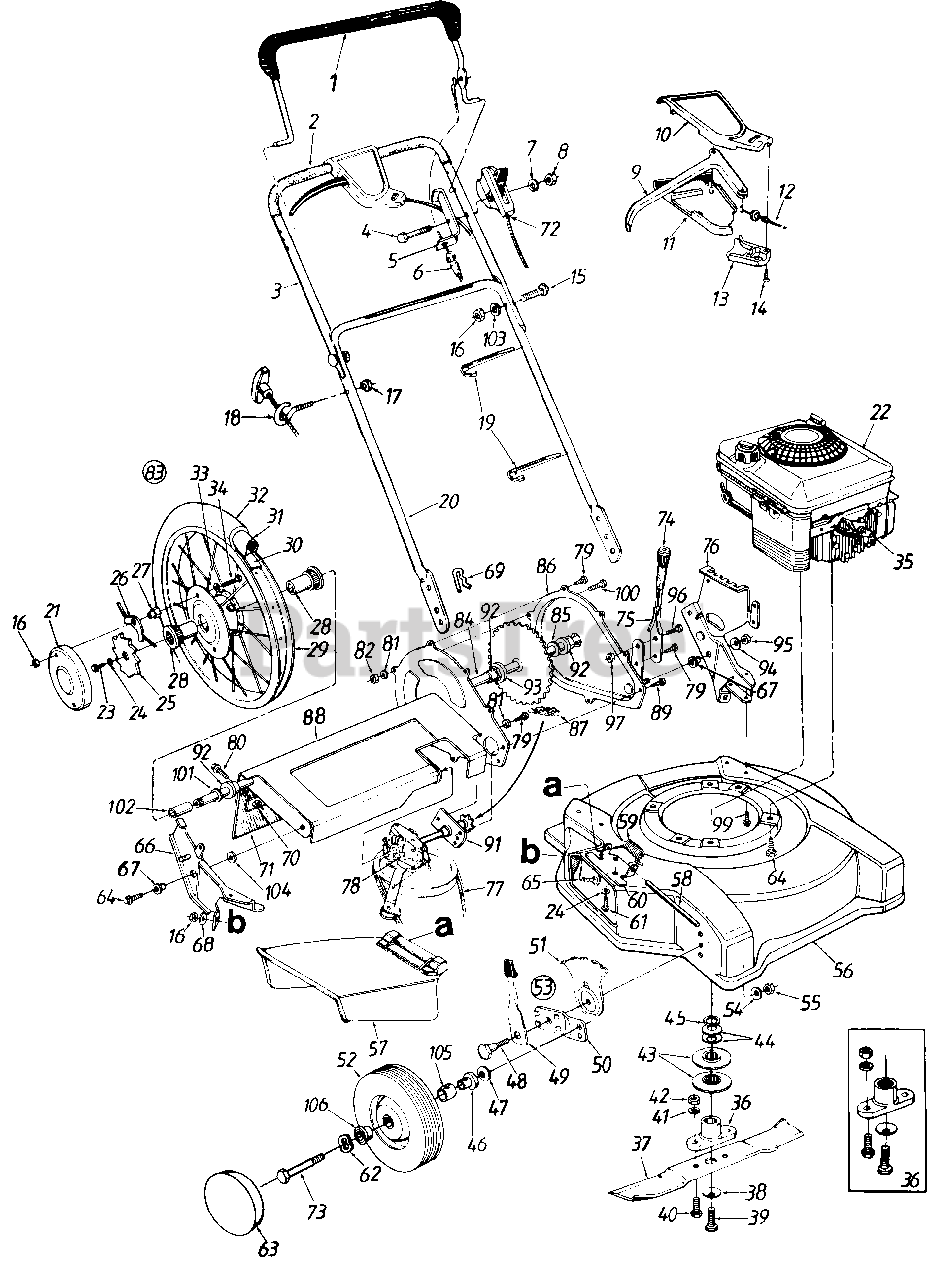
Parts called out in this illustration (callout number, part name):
1	Control Handle Ass'y.
2	Foam Grip
3	Upper Handle
4	Hex Bolt 1/4-20 x 1.875" Lg.
5	Cable Mtg. Brkt.
6	Control Cable-36" Lg.
7	Spring Wash. .265" I.D.
8	Hex Nut 1/4-20 Thd.
9	Control Lever
10	Control Cover Half-Upper
11	Control Cover Half-Lower
12	Self-Propelled Cable-44" Lg.
13	Cable Mounting Cap
14	Fl-"C" Sunk Hd. Tap Scr. #10 x .75" Lg.
15	Curved Carr. Bolt 5/16-18 x 1.38" Lg.
16	Hex Nut 5/16-18 Thd.
17	Hex L-Nut 1/4-20 Thd.
19	Cable Tie
20	Lower Handle
21	Wheel Cover
22	Engine
23	Hex Bolt 1/4-20 x .75" Lg. (Gr. 5)
24	Bell-Wash. 1/4" I.D.
25	Wheel Ratchet
26	Pawl and Spring Ass'y.
27	Special Hex Nut 5/16-18 Thd.
28	Flange Bearing .63" I.D.
29	Rim Ass'y. Only 16" x 2.1"
30	Rimstrip 16" x 7/8"
31	Inner Tube 16" x 2.12"
32	Chevron Tire 16" x 2.125"
33	Intern. L-Wash. 5/16" I.D.
34	Hex Bolt 5/16-18 x 1.0" (Gr. 5)
35	Spark Plug Boot
36	Blade Adapter Kit
37	22" Blade
38	Bell-Wash. .46" I.D.
39	Hex Bolt 7/16-20 x 1.5" Lg. (Gr. 5)
40	Hex Bolt 3/8-24 x 1" Lg.
41	L-Wash. 3/8" I.D.
42	Hex Nut 3/8-24 Thd.
43	Pulley Half
44	Bell-Wash. 1.01" I.D.
45	Crankshaft Spacer
46	Ball Bearing 1/2" I.D.
47	Bell-Wash. .38" I.D.
48	Shld. Bolt.5"
49	Spring Lever Ass'y. w/Knob
51	HeightAdj. Plate
52	Wheel Ass'y. Comp.
53	Height Adj. Ass'y. Comp.-R.H.
54	Bell-Wash. .39" I.D. x 1.38"
55	Hex Nut 3/8-16 Thd.
58	Hinge Pin
59	Torsion Spring
60	Adapter Plate
61	Hex TT-Tap Scr. 1/4-20 x .5"
62	Wave Wash. .53" I.D. x .78"
64	Hex TT-Tap Scr. 3/8-16 x 1"
65	Carriage Bolt 5/16-18 x .62" Lg.
66	Handle Brkt. Ass'y.-R.H.
67	Shld. Spacer .5" x .10"
68	Bell-Wash. 5/16" I.D.
69	Intern. Cotter Pin 5/16" Dia.
70	Retaining Strip
72	Throttle Control Ass'y. Comp.-49" Lg.
73	Front Axle Bolt
75	HeightAdjustment Lever
78	Transmission Comp.
79	Hex B-Tap Scr. 1/4 x .38" Lg.
80	Hex AB-Tap Scr. 1/4 x .62" Lg.
81	L-Wash. 1/4" I.D.
82	Hex Nut 1/4-20 Thd.
83	Wheel Ass'y. Comp.
84	Sprocket and Axle Ass'y.
85	Fl-Wash. .635" I.D. x 1.0" O.D.
92	Hex Flange Brg. .631 " 1 .D.
93	Spacer .63" I.D. x 1.25"
94	Fl-Wash. .385" 1 .D. x .87" O.D.
95	Hex L-Nut 3/8-24 Thd.
96	Hex Bolt 3/8-16 x .62" Lg.
97	Flanged L-Nut 3/8-16 Thd.
99	Hex B-Tap Scr. 5/16-18 x .5"
100	Hex Bolt 1/4-20 x .5" Lg.
101	Fl-Wash. .632" I.D. x .943"
102	Spacer .628" I.D. x .875"
103	L-Wash. 1/4" I.D.
104	Fl-Wash. .38" I.D. x 1" O.D.
105	Spacer .375" I.D. x 1.04" O.D.
106	Ball Bearing 3/8" I.D.
